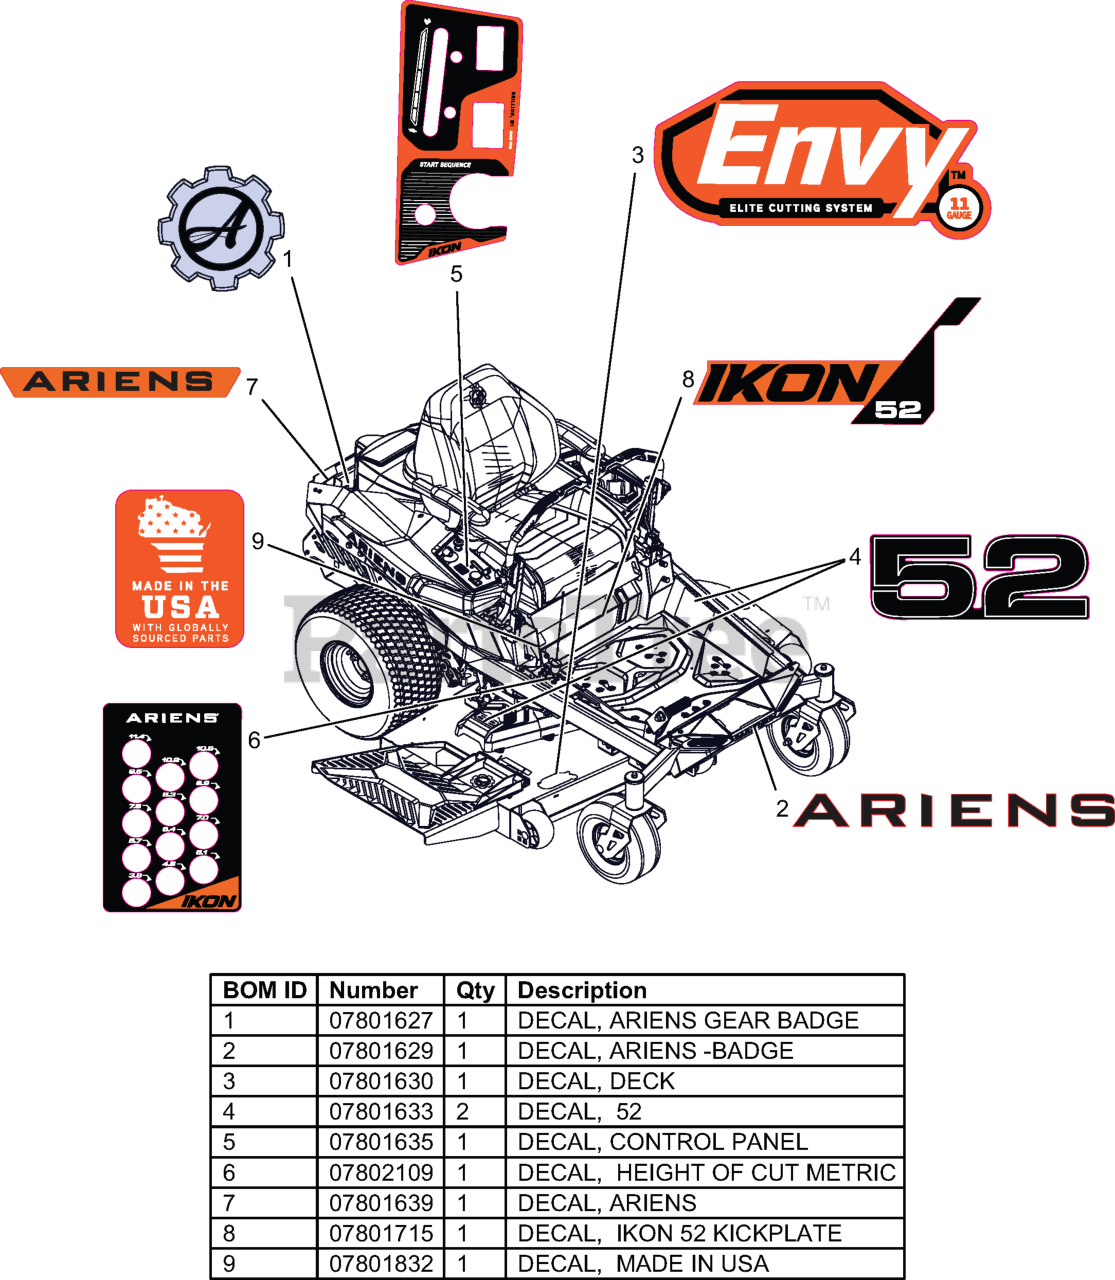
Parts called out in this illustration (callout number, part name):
1	DECAL- ARIENS GEAR BADGE
2	DECAL- ARIENS-BADGE
3	DECAL- DECK
4	DECAL- 52
5	DECAL- CONTROL PANEL
6	DECAL, HEIGHT OF CUT METRIC
7	DECAL- ARIENS
8	DECAL- IKON 52 KICKPLATE
9	DECAL- MADE IN USA
